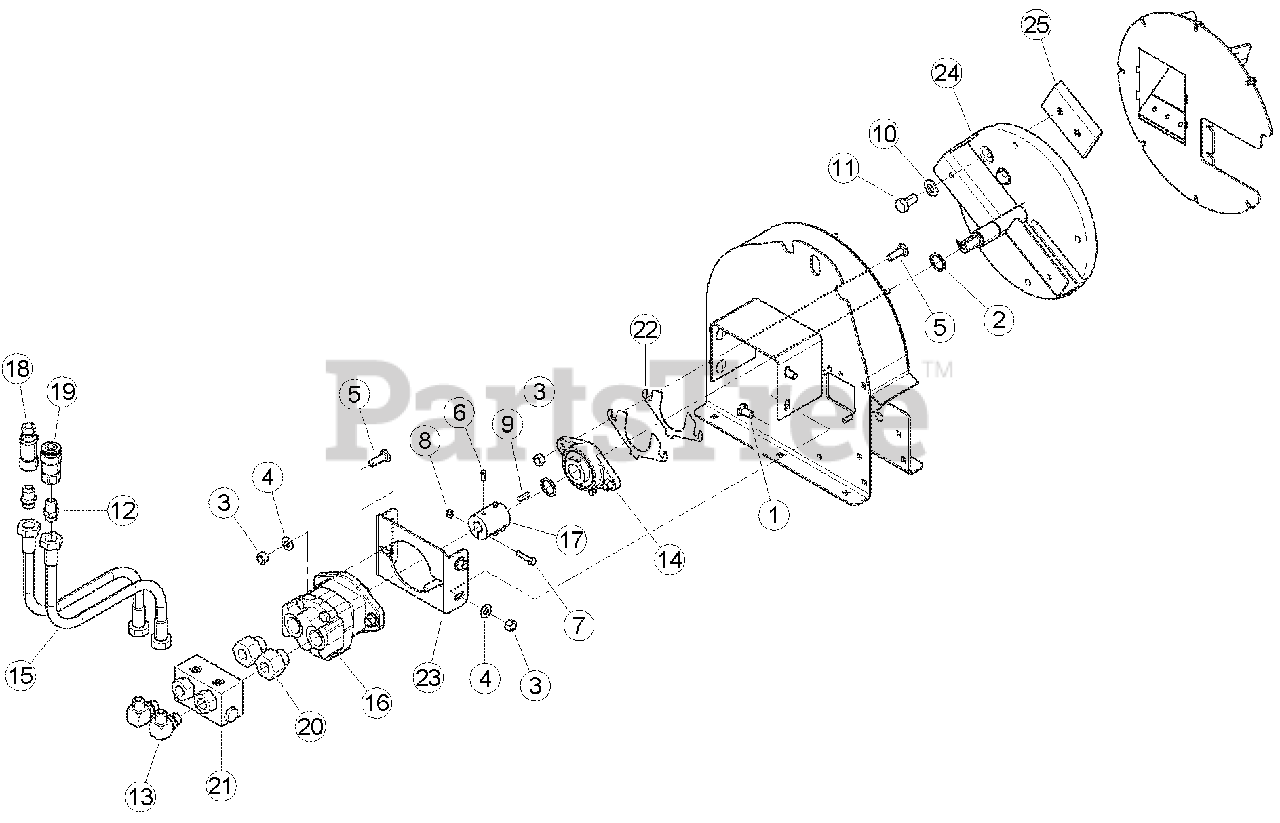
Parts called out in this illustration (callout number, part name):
1	BOLT, 1/2 X 1 CRG GR5 ZP
2	SNAP RING, 1-1/4 EXT. HEAVY DUTY
3	NUT, 1/2 CENTERLOCK GRB ZP
4	WASHER, 1/2 SAE FLAT ZP
5	BOLT, 1/2 X 1-1/2 CRG GR5 ZP
6	SET SCREW, 1/4 X 5/8 SQ HD
7	BOLT, 5/16 X 1-1/2 HEX HD GR5 ZP
8	NUT, 5/16 NE NYLOCK ZP
9	KEY, 1/4 SQUARE X 1 LONG
10	WASHER, 5/8 SAE HARDENED
11	BOLT, M16 X 2.0 X 30 HEX HD W/PATCH
12	ADAPTER, -10 MORING / -10 MJIC
13	ADAPTER, -10 MORING / -10 MJIC 90 DEG.
14	BEARING, 1-1/4" DIA 2 BOLT FLANGE
15	HOSE, .63 X 46" -10 FMJIC SW / -10FMJIC SW
16	MOTOR, .93 CU. IN. HYD
17	COUPLER, 7/8 SPLIT
18	COUPLER, MALE PRESSURE CONNECT
19	COUPLER, FEMALE CONNECT
20	ADAPTER, -16 MORING / -10 FMORING
21	MANIFOLD, OVERRUN AND REVERSE CHECK -10
22	SHIM, BEARING
23	PLATE, MOTOR MOUNT
24	WELDMENT, 4-1/2 HYD DISK
25	KIT, 4-1/2 CHIPPER BLADE KIT
